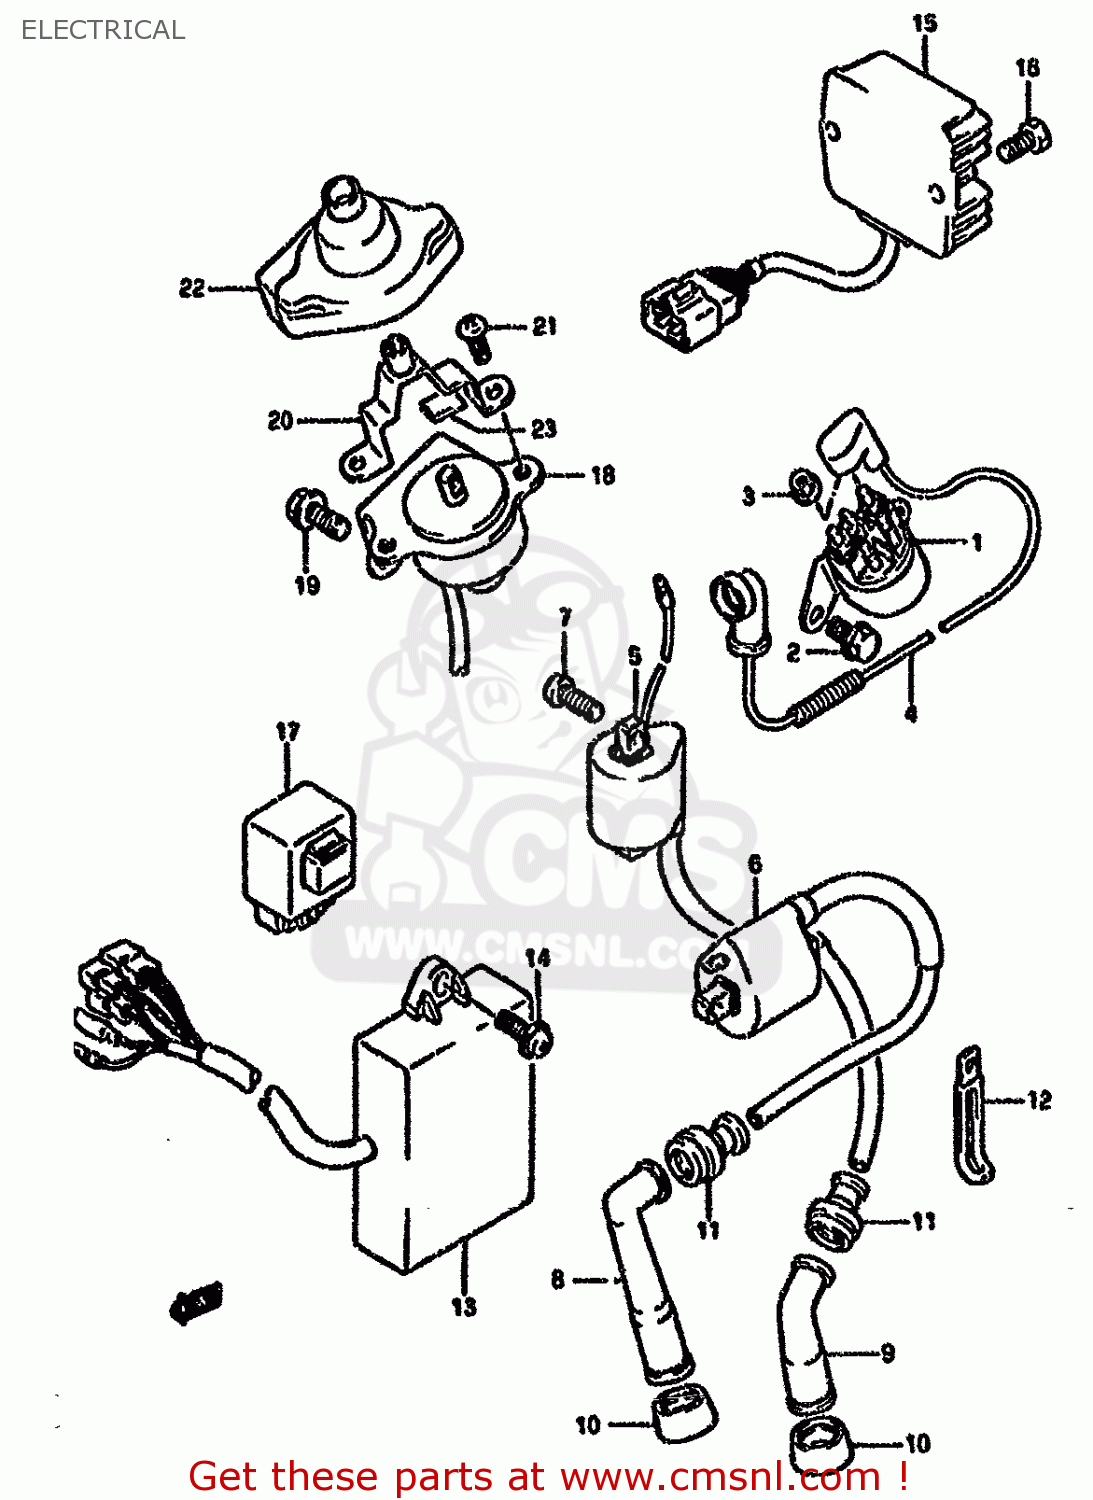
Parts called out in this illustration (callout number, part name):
1	RELAY ASSY,STARTING MOTOR
2	BOLT
3	NUT
4	WIRE,STARTER MOTOR LEAD
5	COIL ASSY,IGNITION
6	COIL ASSY,IGNITION
7	SCREW
8	CAP ASSY,SPARK PLUG
9	CAP,SPARK PLUG
10	SEAL,SPARK PLUG CAP
11	SEAL,HIGH TENSION CORD
12	CLAMP
13	CDI UNIT
14	SCREW
15	RECTIFIER ASSY
16	SCREW
17	CONTROL UNIT,DECOMP
18	SOLENOID ASSY,DECOMP
19	BOLT
20	HOLDER,DECOMPRESSION CABLE
21	SCREW
22	COVER,DECOMP
23	CUSHION,BATTERY(80X27X3)
